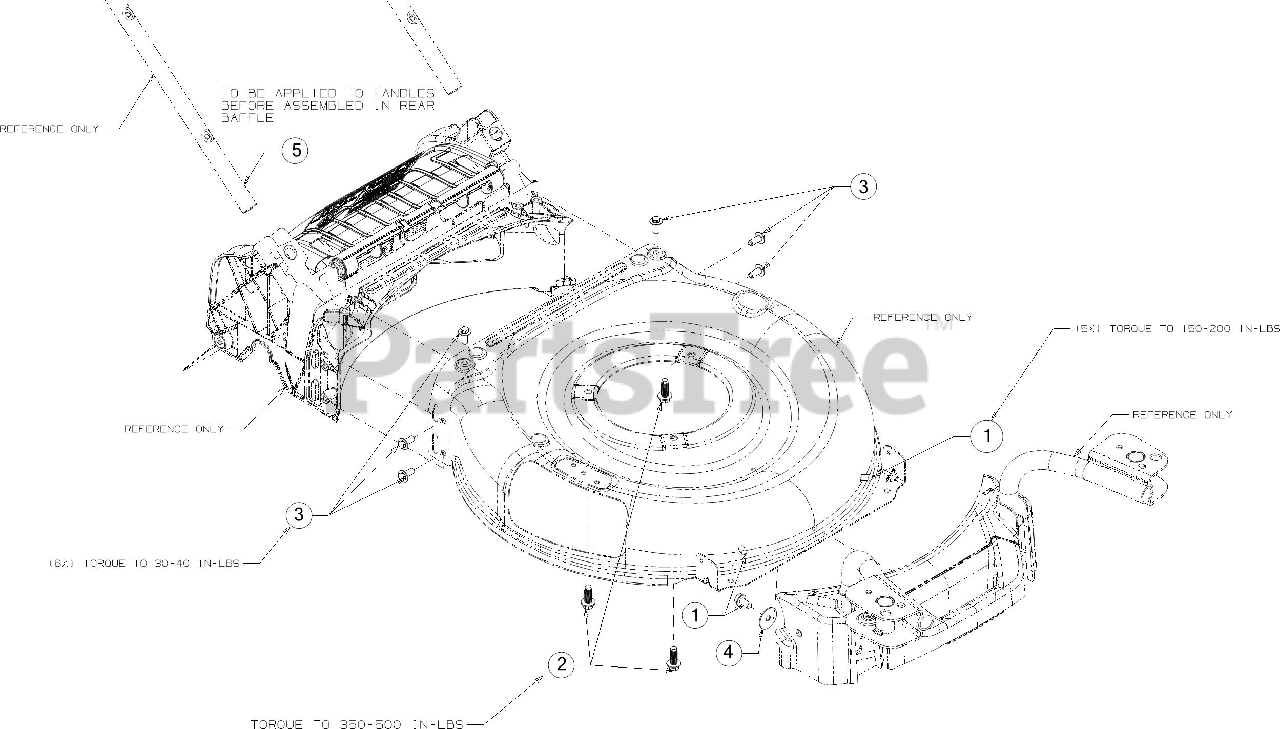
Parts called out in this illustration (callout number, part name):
1	SCREW 5/16-18 X .750
2	SCREW 3/8-16 X 1
3	SCREW 5/16-14 X .750
4	FLAT WASHER .322 ID X 1.25 X .060
5	GREASE
